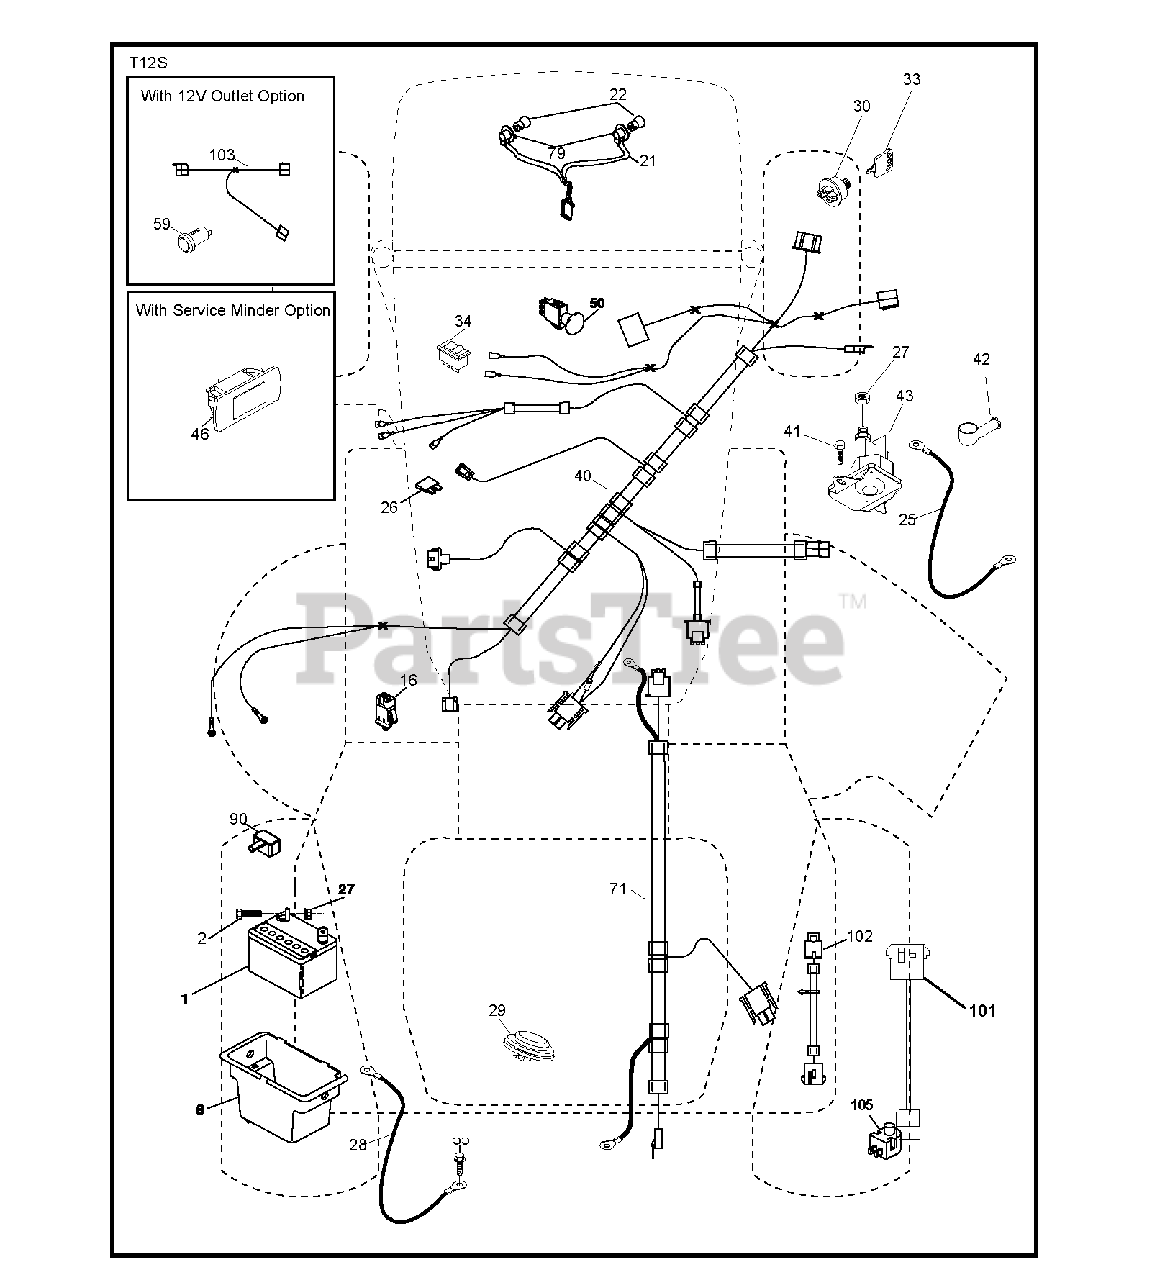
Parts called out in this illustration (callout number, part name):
1	REPL BY 532 12 38-99
8	BOX.BATTERY.MNT.REAR.L
16	SWITCH INTERLOOK PUSH-IN
21	HARNESS.LIGHT W/4152J BULBS
22	LIGHTBULB
25	CABLE.STARTER.6GA.BL/RED.14.
26	FUSE 20AMP
27	NUT
28	CABLE.BLACK.18"REAR.BA
29	SWITCH.SEAT.DELTA.OPC.
30	SWITCH.IGN.DELTA.W.LGH.ROS
33	KEY.CHAIN.BLISTER.PACK.GEN.USA
34	SWITCH LT
40	HARNESS.IGN.DASH.HUQ/P
41	SCREW
42	TERMINAL COVER
43	SOLENOID.W/BRASS.PLUNG
46	GUAGE.SRVCMNDR.HRMTR.
50	PTO SWITCH
55	SCREW 5/16"
71	HARNESS.IGN.CHASS.TEX.REAR.BAT
79	BULB HOLDER ASM.
90	COVER, TERMINAL BATTERY
102	HARNESS PIGTAIL PCH TEX ROS
105	REVERSE SWITCH
